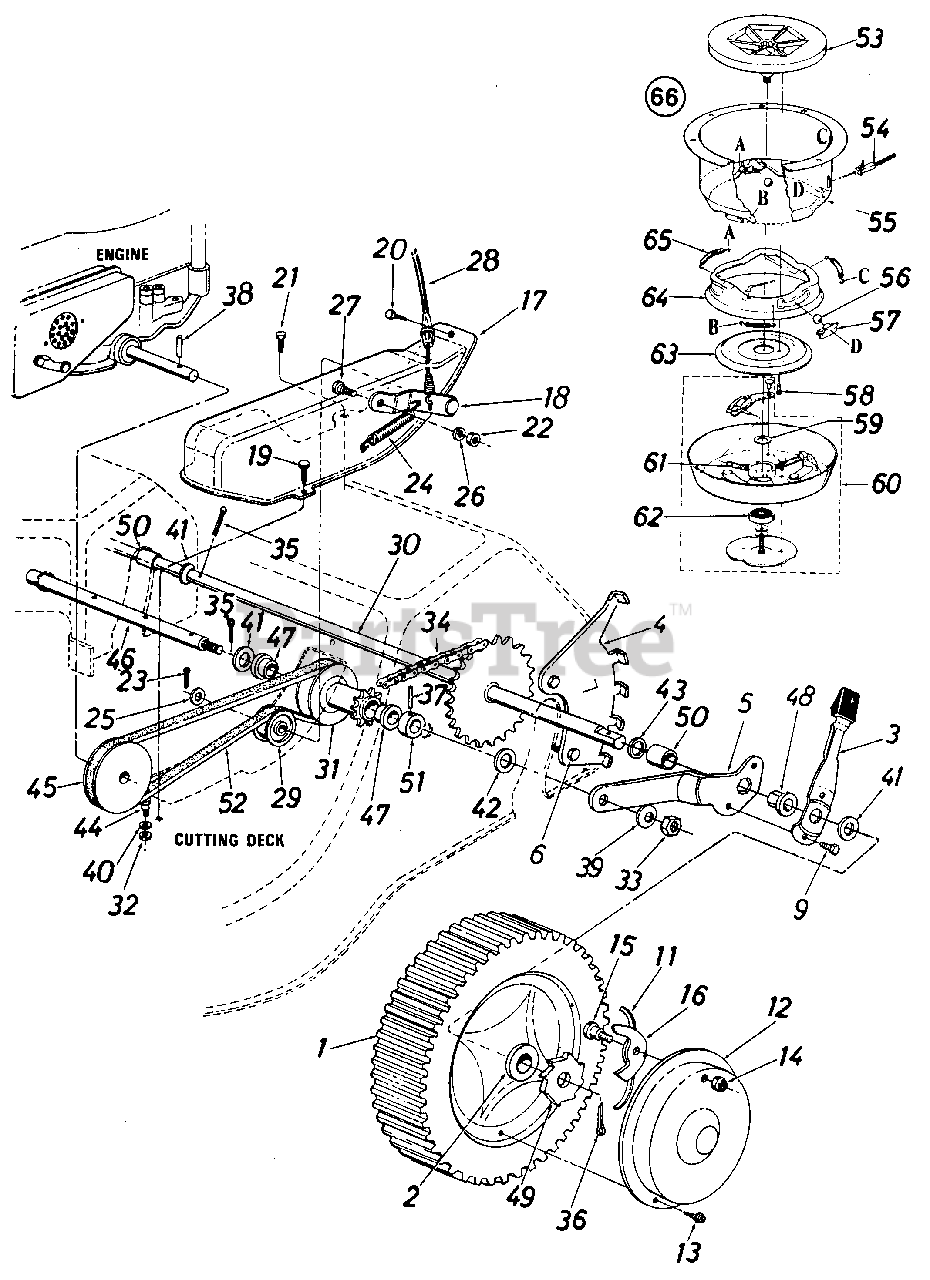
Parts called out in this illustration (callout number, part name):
1	WHEEL ASSY W/TIRE
2	BEARING-BALL
3	LEVER-SPRING
4	PLATE-INDEX-RR-LH
5	BRACKET-PIVOT-LH
6	SCREW-HEX L-WASH HD
9	SCREW-HEX B-TAP 1/4 X .38
11	SPRING-NYLON
12	HUB CAP
13	SCREW-PAN HD TAPP
14	NUT-INS LOCK 1/4-20
15	SCREW-SHLD .342 DIA X .268
16	PAWL
17	GUARD-BELT
18	BRACKET ASSY-IDLER
19	SCREW-HEX WASH SF TAPP
20	SCREW-HEX DRILLING #10 X .50
21	SCREW-HEX HD TAP 1/4-20 X 7.5
22	NUT-HEX 1/4-20
23	PIN-COTTER-1/8 DIA X 1.00
24	SPRING-EXTENSION
25	WASHER-FL-.531 X .930 OD X .050
26	LOCK WASHER 1/4 DIA
27	SCREW-SHLD
28	CABLE-CLUTCH
29	PULLEY-IDLER-FLAT
30	SHAFT ASSY-REAR
31	PULLEY W/SPROCKET-9T
32	NUT-HEX 5/16-18
33	NUT-HEX JAM 3/8-18
34	#48 CHAIN 1/2 PITCH X 31 LINKS
35	PIN-COTTER-3/32 DIA X 1.00
36	PIN-COTTER-1/8 DIA X 1.00
37	PIN-SPRING SPIR 3/16 X 1.00
38	PIN-SPIROL 3/16X1.50
39	WASHER-BELL .400 ID X .88 X .060
40	WASHER-LOCK-5/16
41	WASHER-FL-.531 X .930 OD X .050
42	WASHER-BELL .3/8ID X 1.12OD X .030
43	WASHER-FL
44	SCREW-SHLD .437 DIA X .350
46	SHAFT-PULLEY
47	BEARING-FLANGE
48	BEARING-HEX FLANGE .506 ID
49	RACHET-WHEEL
52	BELT-V 1/2 X 33
53	ADAPTER-FAN
54	CABLE-CLUTCH
55	HOUSING-CLUTCH
56	BALL-STEEL
57	BALL-BLOCK
58	SCREW-HEX WASH 1/4-20X.75
59	WASHER-FL .687 X 1.060 X .032
60	HOUSING-CLUTCH BLADE
62	CONE-CLUTCH
63	CONE-CLUTCH
64	CONE-BRAKE CUP
65	SPRING-EXTENSION
66	CLUTCH ASSY-BLADE
